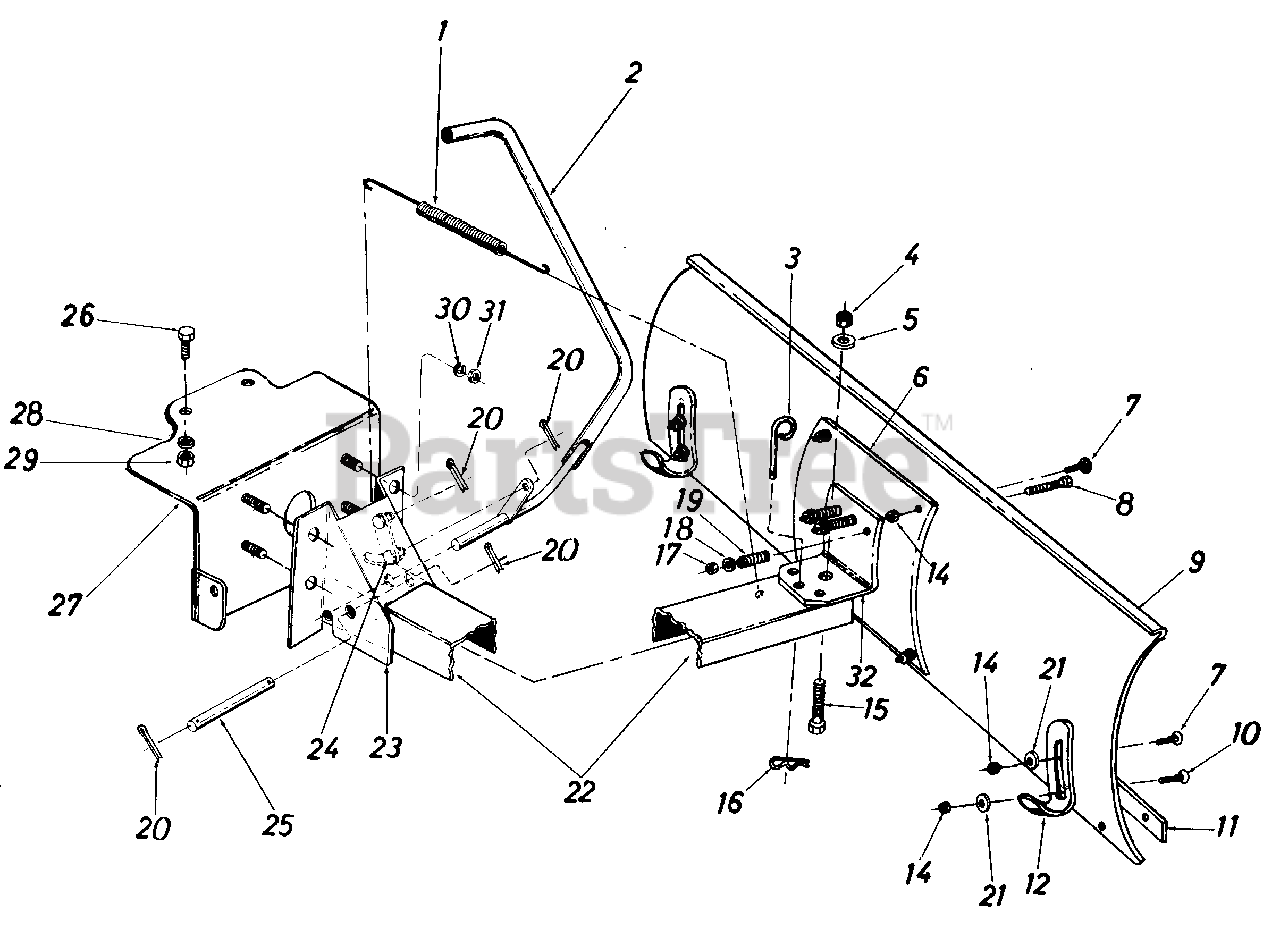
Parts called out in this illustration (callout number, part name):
1	Extension Spring
2	Lift Handle Ass'y.
3	Pivot Lock Pin
4	Hex Cent. L.-Nut 1/2-13 Thd.
5	Fl.-Wash. 17/32 I.D. x 1.25" Lg.
6	Reinforcement Plate
7	Carriage Bolt 5/16-18 x .75" Lg.*
8	Hex Scr. 3/8-16 x 3.75" Lg. Grade 5
9	42" Blade
10	Carriage Bolt 5/16-18 x 1.00" Lg.*
11	42" Wear Plate
12	Shoe Skid
14	Hex Cent. L.-Nut 5/16-18 Thd.*
15	Hex Scr. 1/2'-13x 1.25" Lg.*
16	Hair Pin Cotter
17	Hex Cent. L.-Nut 3/8-16 Thd.
18	Fl.-Wash. 3/8" I.D.
19	Compression Spring
20	Cotter Pin 1/8" Dia. x 1.00" Lg.*
21	Fl.-Wash. 5/16" I.D.
22	Push Bar Channel
23	Pivot Support Bracket
24	Lift Link
25	Channel Pivot Shaft
26	Hex Scr. 3/8-16 x 1.00" Lg. Grade 5
27	Support Bracket Ass'y.
28	L.-Wash. 3/8 I.D.*
29	Hex Nut 3/8-16 Thd.*
30	L.-Wash. 3/8" I.D.*
31	Hex Jam Nut 3/8-16 Thd.
32	Support Bracket
